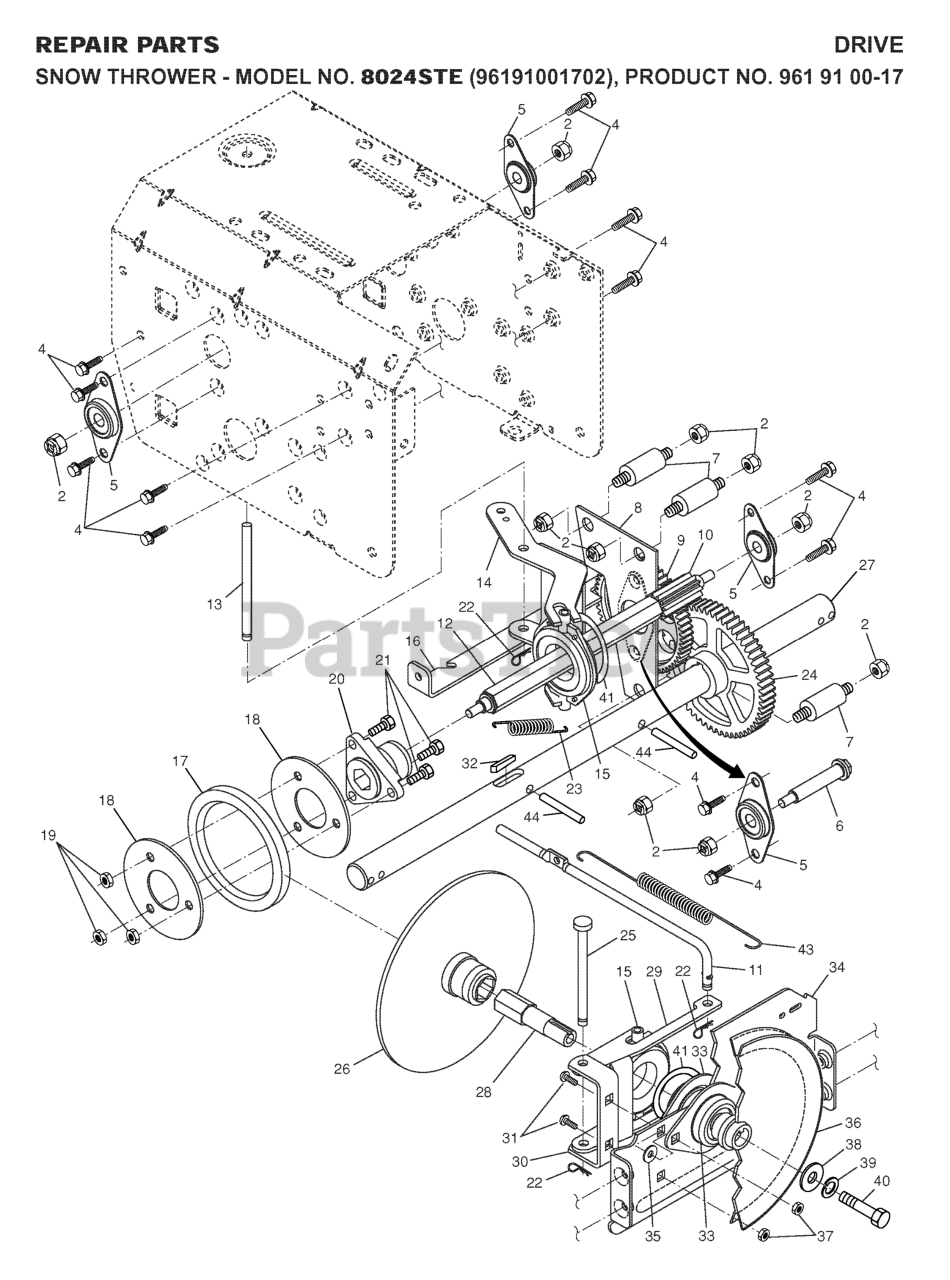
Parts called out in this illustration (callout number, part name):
2	NUT.LOCK.5/16-18
4	Screw 5/16-18 x 1/2 Hex, Self Tapping 5/16-18 x 1/2
5	BEARING, FLANGE
6	SHAFT, AUXILIARY
7	SPACER, PLATE
8	AUXILLARY PLATE
9	GEAR, INTERMEDIATE
10	GEAR, PINION
11	ROD.CLUTCH.YELLOW.ZINC
12	SHAFT.HEX.LONG
13	PIN, PIVOT
14	LEVER, SPEED CONTROL
15	TRUNNION BEARING ASSY
16	BRACKET, PIVOT, SHIFT
17	RING, RUBBER WHEEL
18	PLATE.RUBBER.WHEEL
19	NUT.CENTERLOCK.5/16-
20	HUB, RUBBER WHEEL
21	BOLT
22	RETAINER CLIP PM
23	SPRING, BIAS
24	GEAR, AXLE (58T)
25	PIN, PIVOT LEVER
26	DRIVE PLATE WELDMENT
27	SHAFT.AXLE.16".SNOW
28	SHAFT.HEX.SHORT
29	LEVER.SHIFTER.PLATE.BLACK
30	BRACKET, SHIFTER SUPPORT
31	BOLT
32	KEY, SQUARE 1/4 X .875
33	BEARING FLANGE
34	PLATE.DRIVE.MOUNTING.BLACK
35	SPACER, BEARING
36	PULLEY.TRACTION.7.75
37	NUT.FLANGE.5/16
38	WASHER, FLAT
39	WASHER.LOCK.HVY.HLCL.SPR.5/16
40	Screw, Hex Head 5/16-18 x 3/4
41	RETAINING RING (2 2)(3 2)
43	SPRING.RETURN
44	PIN.ROLL.3/16
